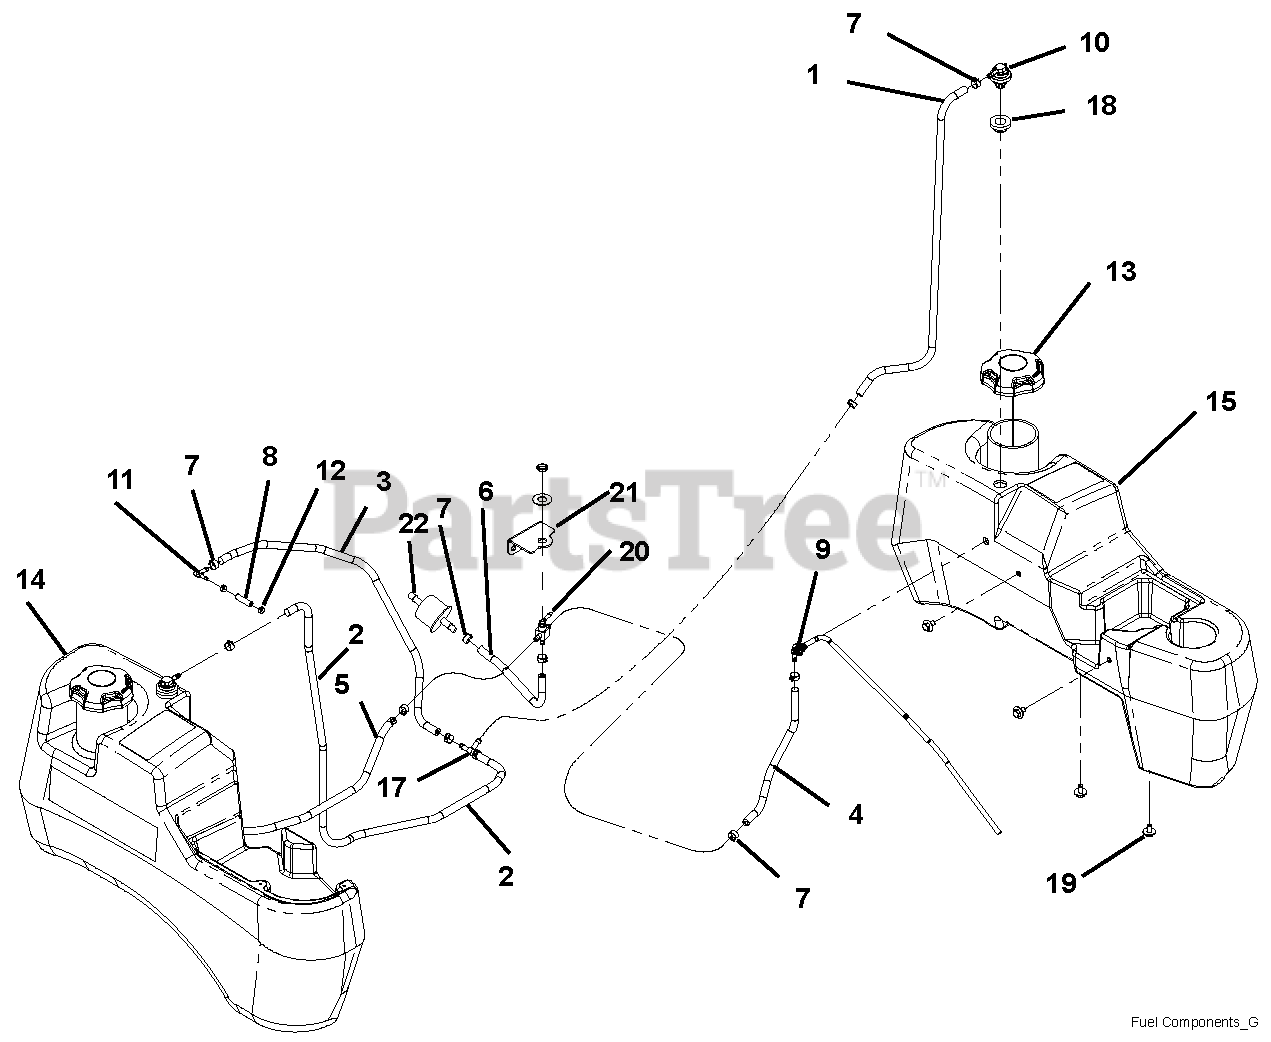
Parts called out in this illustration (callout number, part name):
1	Hose, .25 Low-Perm Bulk Gas
2	Hose, .25 Low-Perm Bulk Gas
3	Hose, .25 Low-Perm Bulk Gas
4	Hose, .25 Low-Perm Bulk Gas
5	Hose, .25 Low-Perm Bulk Gas
6	Hose, .25 Low-Perm Bulk Gas
7	Clamp, Fuel Line
8	Hose, .188 Low-Perm Bulk Gas
9	Assembly, Large Tank Fuel Pick-Up
10	Valve, Combination
11	Fitting, 3/16 x 1/4 90 Degree Vac
12	Clamp, Hose, Spring .188
13	Cap, Fuel, Nonvent Autoclick
14	Tank, RH Large Gravely Fuel
15	Tank, LH Large Gravely Fuel
16	Label, EPA Non-Compliant Tank
17	Tee, 1/4 HS Run x 1/4 HS Branch
18	Grommet, Remote Vent Rev
19	Bolt, SEMS .31-18 x .62
20	Valve, Fuel (Nut and washer shown are included with valve)
21	Bracket, Valve
22	Fuel Filter
